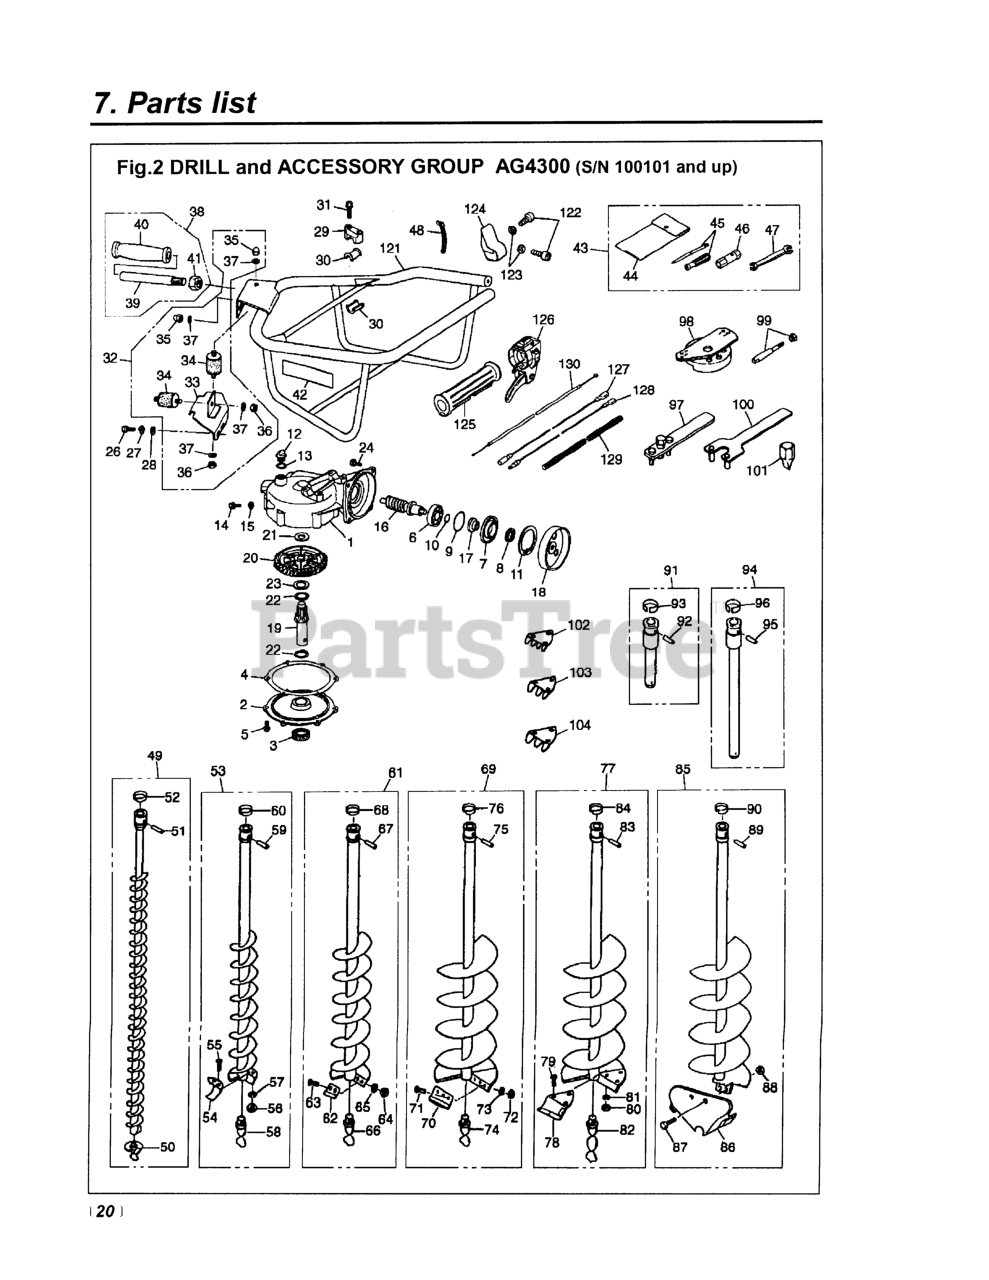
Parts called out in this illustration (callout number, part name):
1	GEARCASE COMP (RPLS -11102)
2	COVER COMP (RPLS -11202)
3	SEAL, OIL
4	GASKET
7	RETAINER
9	O-RING
11	RING, SNAP, M62 x 2.0
19	SHAFT
24	BOLT, M6 x 20
28	WASHER, M6 X 2.3
30	SPACER
31	BOLT, M6 x 30
32	BRACKET ASSY (RPLS-31201)
36	NUT, M6 X 5
37	WASHER, M6 X 15
38	HANDLE COMPLETE
39	HANDLE-L
41	NUT, M14 x 11
42	NAME PLATE
43	TOOL SET
45	SCREWDRIVER
47	SPANNER, 8 X 10 (RPLS 2540- )
48	BAND
49	S40 DRILL ASS
51	PIN
52	CLIP
53	DRILL S60 ASS
55	SCREW, M6 X 20
56	NUT, M6 X 5
57	WASHER, M6 X 15
58	BIT
59	PIN
60	CLIP
61	S90 DRILL ASS
62	TIP, S90
63	SCREW, M6 X 20
64	NUT, M6 X 5
65	WASHER, M6 X 15
66	BIT
67	PIN
68	CLIP
69	S150 DRILL ASS
70	TIP, S150
71	SCREW, M6 X 20
72	NUT, M6 X 5
73	WASHER, M6 X 15
74	BIT
75	PIN
76	CLIP
77	S200 DRILL ASS
78	TIP, S200
79	SCREW, M6 X 20
80	NUT, M6 X 5
81	WASHER, M6 X 15
82	BIT
83	PIN
84	CLIP
85	I150 DRILL ASS
87	BOLT, M6 x 20
88	NUT, M6 X 5
89	PIN
90	CLIP
91	JOINT L100 ASS
92	PIN
93	CLIP
94	JOINT L300 ASS
95	PIN
96	CLIP
98	SET BLOCK (TOOL)
99	ROD ASSEMBLY (TOOL)
121	FRAME
124	BRACKET, FRAME
125	GRIP (RPLS 3577-32140 & 3220-
126	LEVER (USE 848-8R2-0313)
127	CORD
129	TUBE
130	CABLE COMP.
